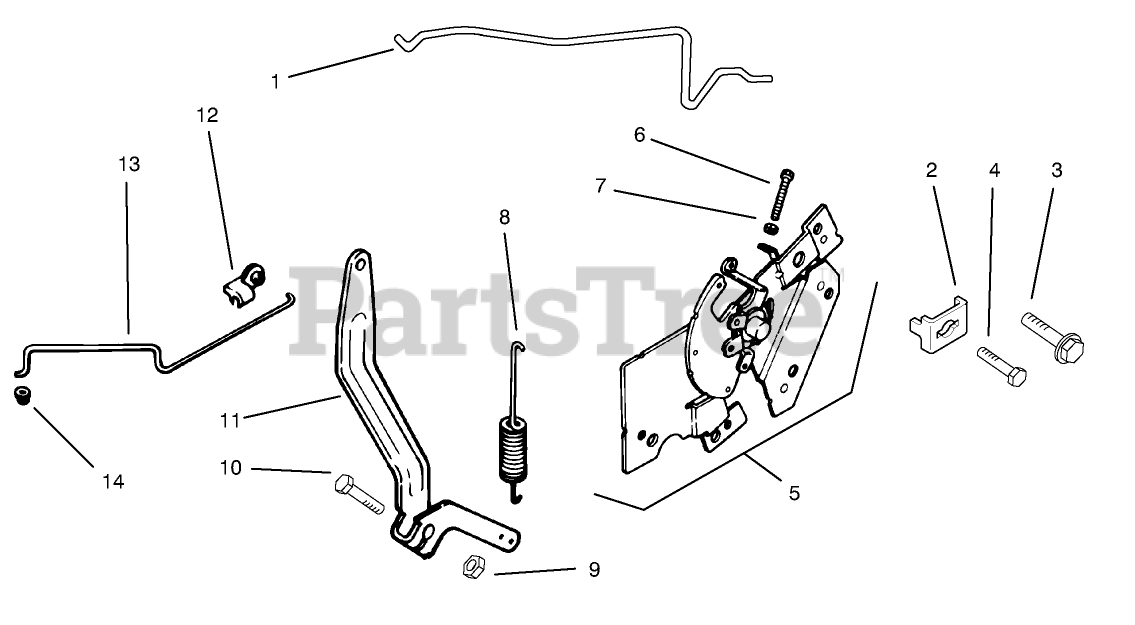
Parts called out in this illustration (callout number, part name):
1	Linkage-Choke (Only On: 72042,72043,72062,72063)
3	Screw Socket
4	Screw M5x0.8x16 (Only On: 72042, 72063, 72062, 72043)
5	Control-ASM INC 6-7 (Only On: 72042, 72063, 72062, 72043)
6	Screw-HHF M4x0.7x28 (Only On: 72042, 72063, 72062, 72043)
7	Nut
8	Spring-Governor (Only On: 72042, 72063, 72062, 72043)
11	Lever-Governor (Only On: 72042, 72063, 72062, 72043)
12	Bushing-Linkage
13	Linkage-Throttle (Only On: 72042, 72063, 72062, 72043)
14	Bushing
